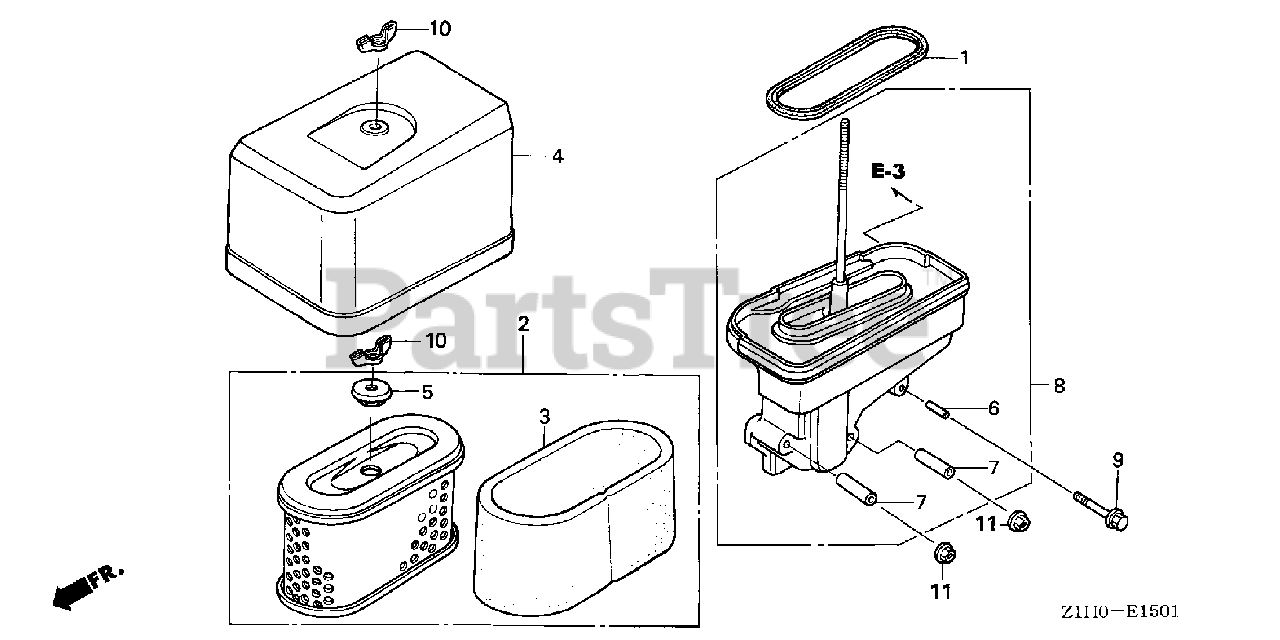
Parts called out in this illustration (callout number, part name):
1	GASKET, ELBOW
2	ELEMENT, AIR CLEANER (METAL BASE)
3	FILTER (OUTER)
4	COVER, AIR CLEANER (DUAL)
5	GROMMET, AIR CLEANER
6	COLLAR, AIR CLEANER
7	COLLAR, AIR CLEANER
8	ELBOW, AIR CLEANER
9	BOLT, FLANGE (6X35) (CT200)
10	NUT, TOOL BOX SETTING
11	NUT, FLANGE (6MM)
